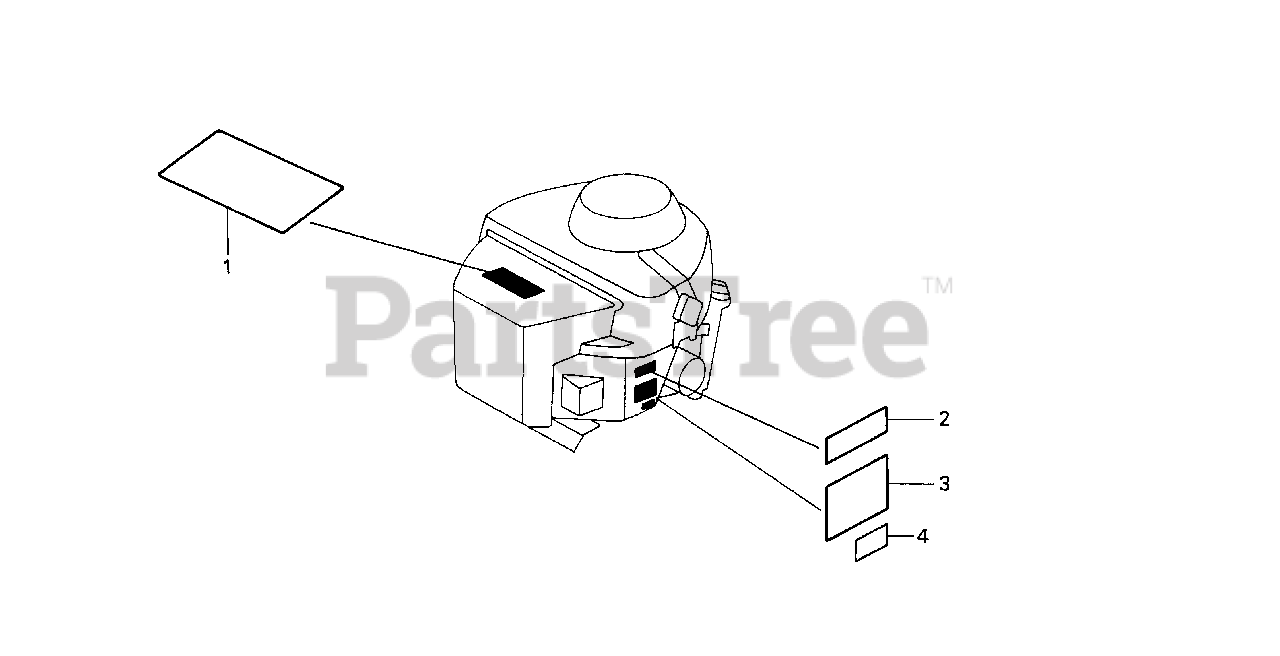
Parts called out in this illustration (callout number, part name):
1	MARK, EMBLEM (GXV620)
2	LABEL, SPECIFICATION (GXV620)
3	LABEL, CAUTION
4	LABEL, FUEL CAUTION
